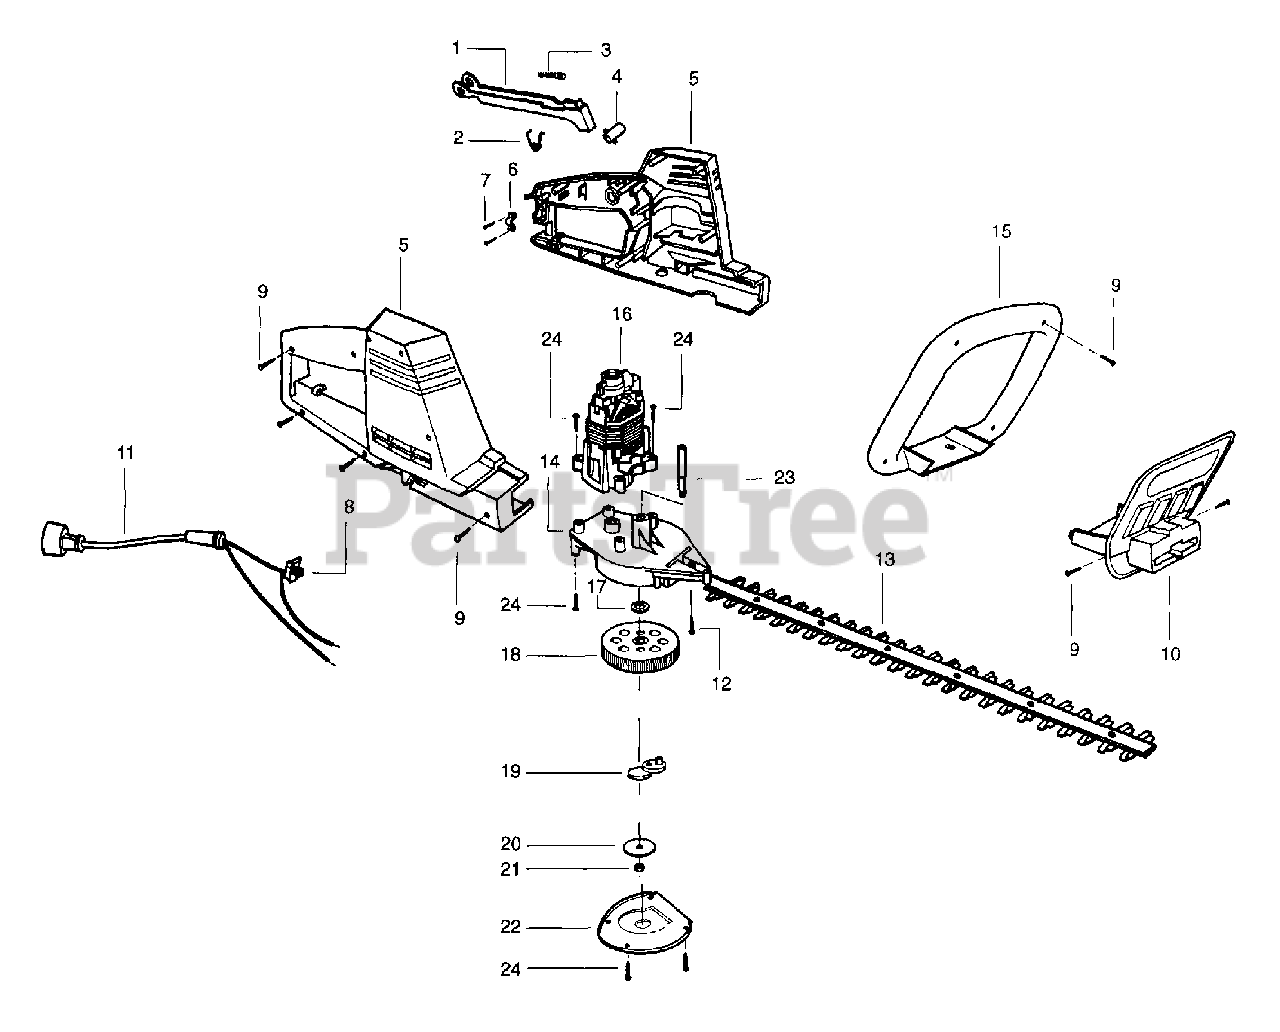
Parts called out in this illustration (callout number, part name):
1	Trigger Switch
2	Spring Clip
3	Spring - Trigger Lock
4	Button - Trigger Lock
5	Housing Set (R & L)
6	Cordset Clamp
8	Switch (On/Off)
13	Blade Ass'y. 18"
13	Blade Ass'y. 22"
14	Gear Box Ass'y.
15	Handle Ass'y.
16	Motor Ass'y.
17	Washer - Thrust
19	Drive Cam
20	Washer - Cam
22	Plate Cover
